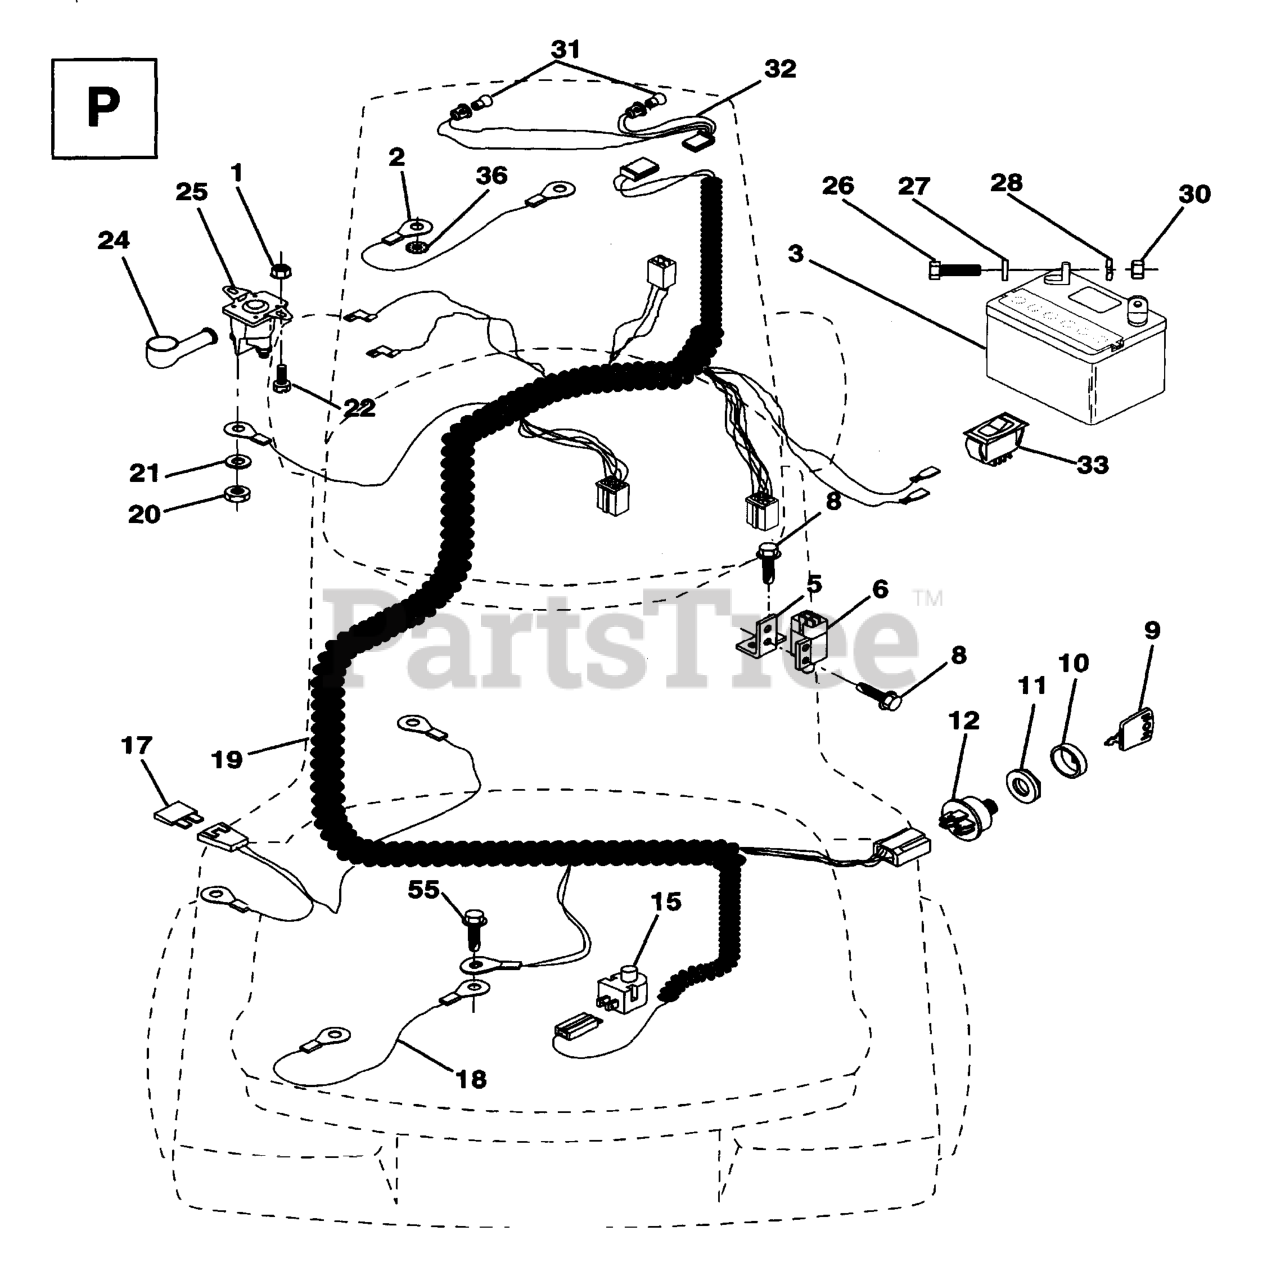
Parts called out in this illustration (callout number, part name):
1	Nut, Keps Blk Hex 1/4-20 UNC
2	CABLE.BATTERY.6GA.16"RED
3	REPL BY 532 12 38-99
5	BRACKET LT
6	SWITCH INTERLOCKT
9	KEY MLD GEN DELTA
10	COVER SWITCH KEY
11	NUT, IGNITION
12	IGNITION SWITCH
15	RP.SWITCH.PLUNGER.NC.GRAY
18	CABLE ASSY
19	HARNESS IGN LR NLA
20	NUT
21	LOCKWASHER
22	BOLT
24	TERMINAL COVER
25	REPL BY 532 10 99-46
26	BOLT.HEX.1/4.X.3/4.DICHROMATE
28	LOCKWASHER
30	NUT
32	HARNESS HEADLIGHT
36	LOCKWASHER
55	Screw 5/16-18 x 1/2 Hex, Self Tapping 5/16-18 x 1/2
70	HARNESS, ENGINE
